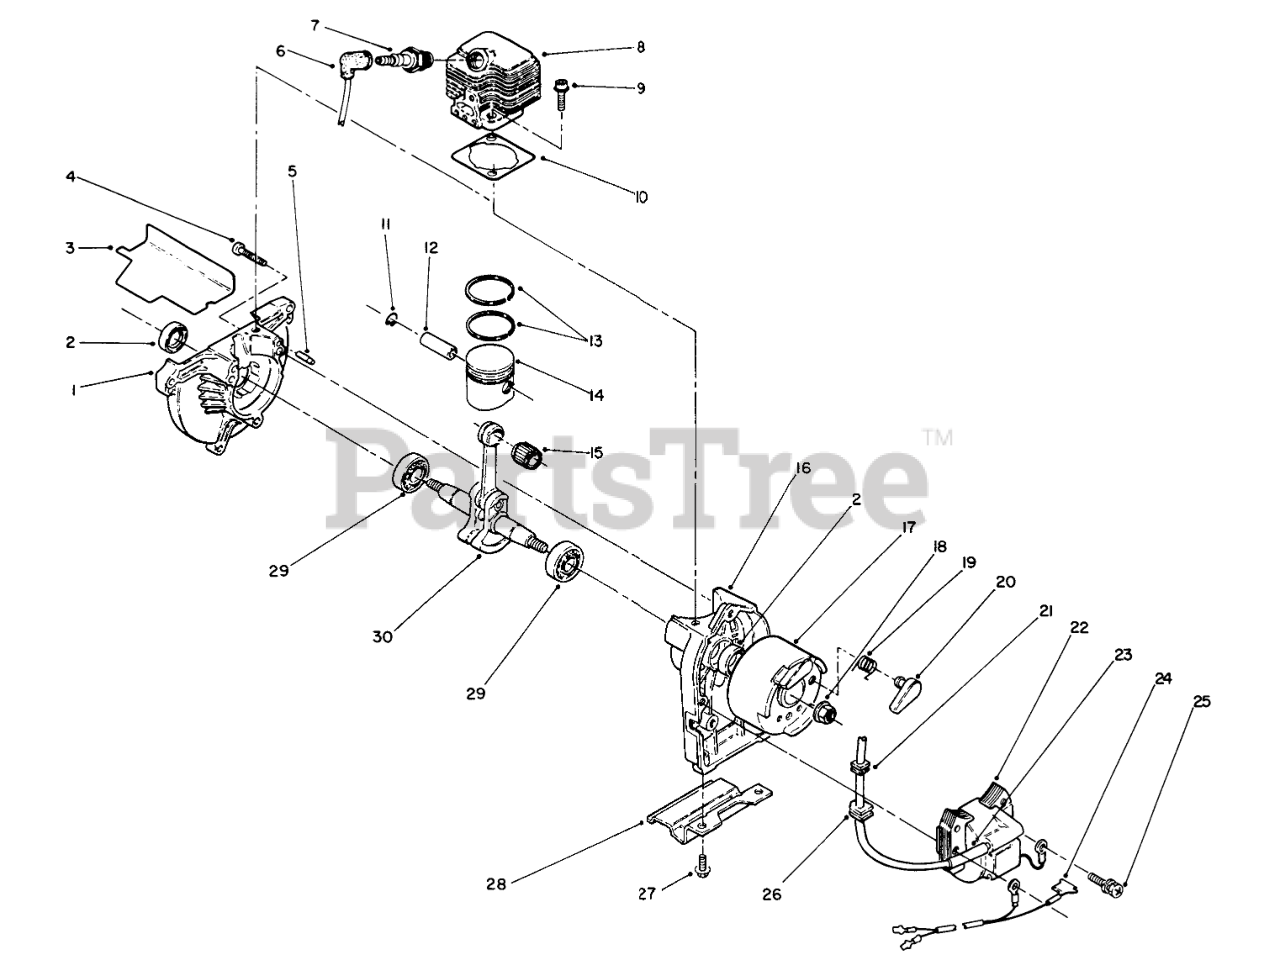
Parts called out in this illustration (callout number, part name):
1	DRIVE CASE
2	OIL SEAL
3	BAFFLE GASKET
4	Screw
6	PLUG BOOT
7	SPARK PLUG (NGK)
8	CYCLINDER
10	Gasket-Cylinder Head
11	CLIP, PISTON PIN
12	PIN, PISTON
13	RING,PISTON
14	Piston Assembly (Incl. Ref. #12)
15	BEARING, NEEDLE
16	STARTER CASE
17	Flywheel Assembly (Incl. Ref. #19 & 20)
19	RETURN SPRING
20	RATCHET
21	GROMMET
22	IGNITION COIL
24	LEAD WIRE
25	BOLT AND WASHER
26	GROMMET
27	SCREW & WASHER
28	STAND SUPPORT
29	BEARING
30	Crankshaft Assembly
